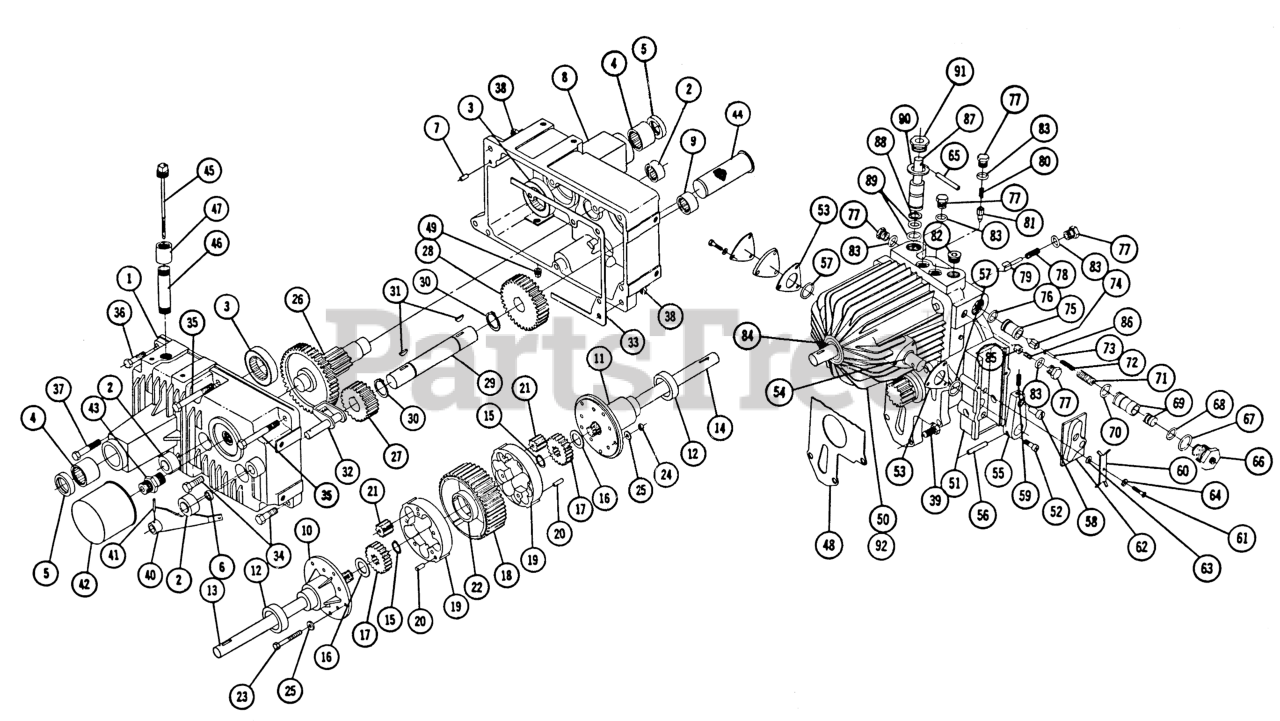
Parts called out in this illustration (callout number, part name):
2	BEARING-NEEDLE
5	SEAL-OIL
7	PIN-DOWEL
17	SIDE GEAR
19	BULLT 252
23	Bolt Hex 3 1/4
24	3/8-16 E.S.
25	Washer
31	Key
36	Bolt 3/8-16 x 2 1/4
37	Bolt Hex 3/8-16 x 1
39	Bolt, 3/8-16 x 1
43	FITTING
46	Nipple 1/2 Pipe x 31/2
47	Coupling 1/2 Pipe
50	SER BULLT 437B
55	Arm-Cam Follower
56	ROLL PIN 1/4 X 1-1/4
59	Set Screw-1/4-20 x 1/2
61	Bolt-Rd. Heed #8-32 x 1/2
62	CAM
63	Washer
64	Lockwasher
65	SPIROL PIN
68	O RING
70	O RING
72	SPRING
78	SPRING-SUNDSTRAND
80	Spring Charge Pump Valve
83	O RING
